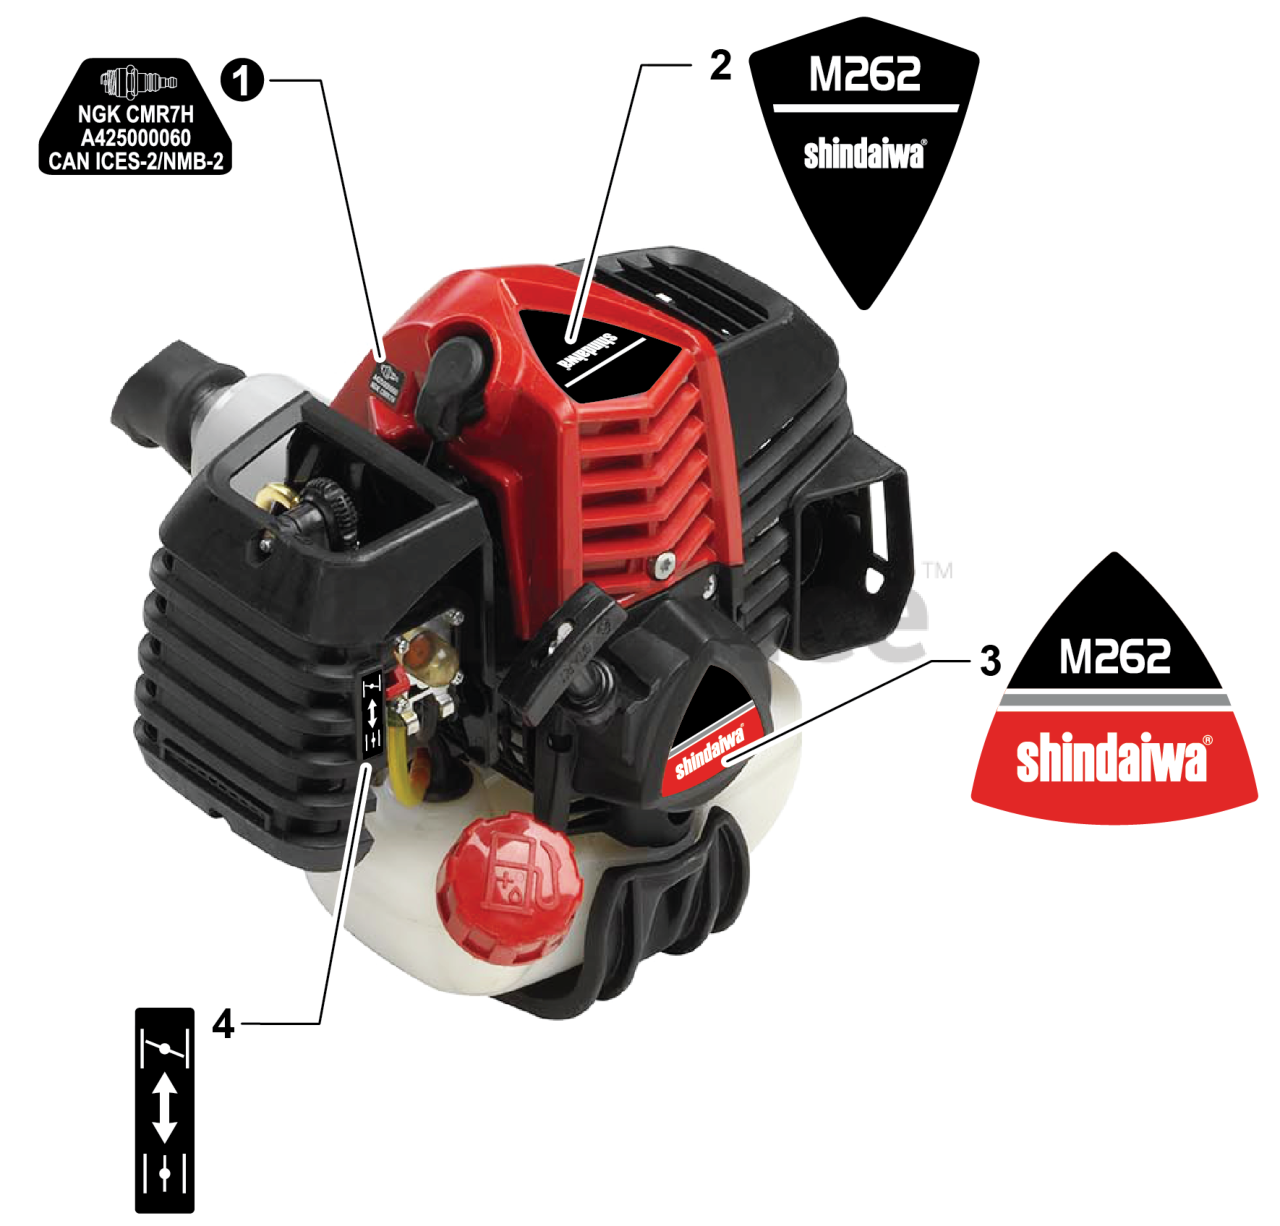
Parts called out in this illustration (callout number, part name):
1	LABEL - SPARK PLUG - CMR7H
2	LABEL - MODEL M262
3	LABEL - RECOIL STARTER - M262
4	LABEL - CHOKE
